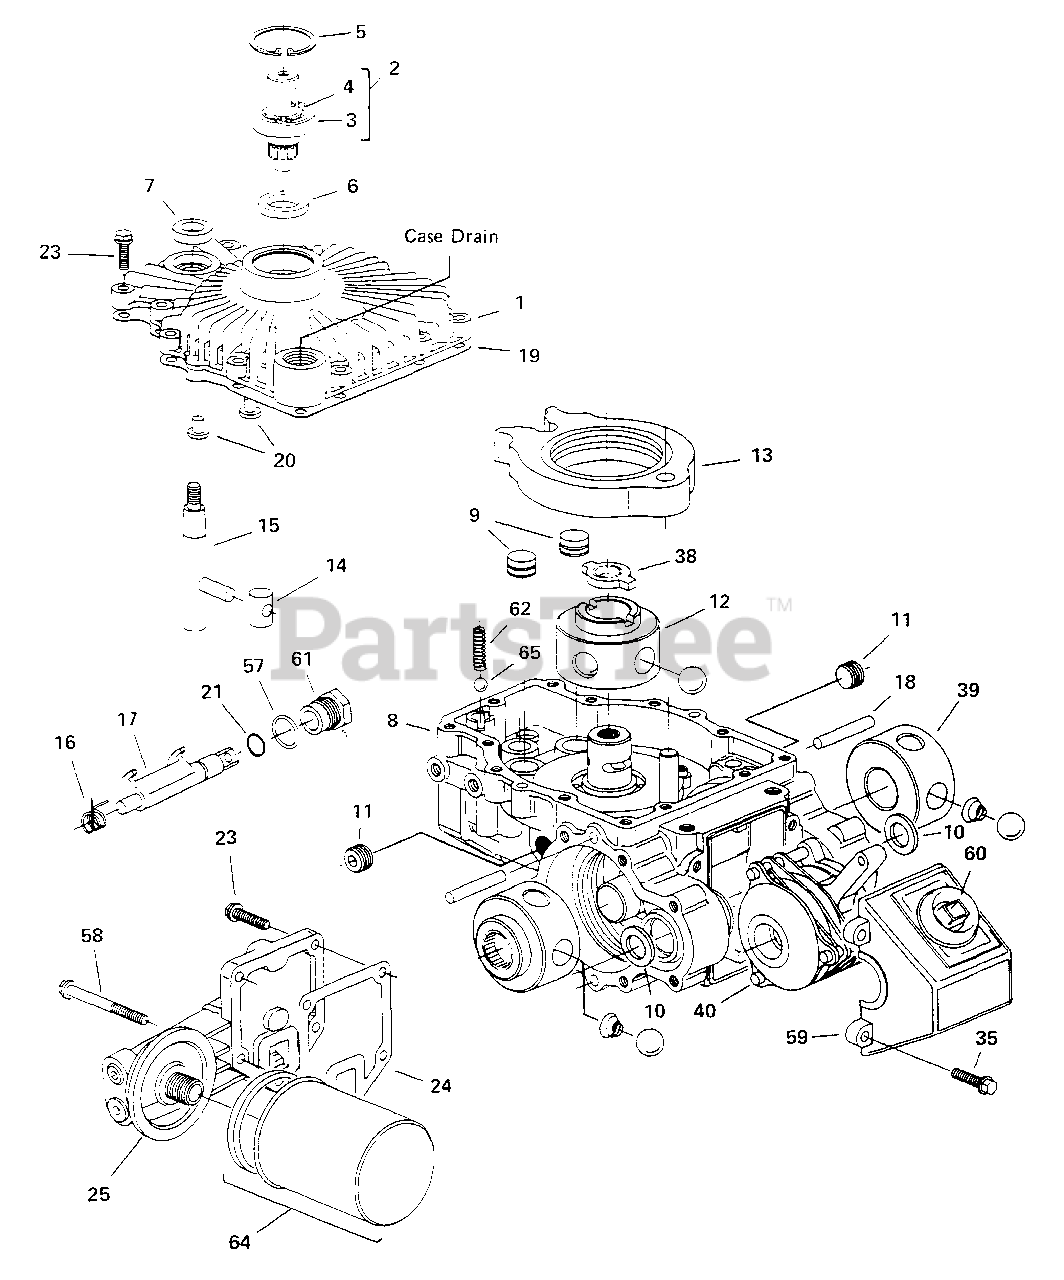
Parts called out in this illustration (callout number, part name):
1	COVER, Subassembly (S/A)
2	SHAFT, Input, S/A (Incl. 3 & 4)
3	BEARING
4	RING
5	RING, Retaining, Internal
8	HOUSING, S/A, Clockwise
9	PISTON, Quieting, S/A
10	SEAL, Lip, Radial
11	PLUG, Socket Pipe
12	PUMP, Rotor-Ball Pin, S/A
13	CAM RING, S/A
15	CONTROL SHAFT, S/A
16	SPRING, Dump Valve
19	GASKET, Cover
23	CAPSCREW, Hex, Flange, 1/4-20
24	GASKET, Filter Base
25	FILTER BASE, S/A
35	SCREW, 1/4-20 Self Tap
39	MOTOR ROTOR-BALL, A & B S/A, 15T
40	BRAKE, Parking, Assembly
57	O-RING, Fitting
58	SCREW, 1/4-20 Hex Flange
59	COVER, Parking Brake
62	SPRING, Relief Valve
64	FILTER, Oil (w/Seal), Special-10 Micron
65	BALL, Grade 200
65	GASKET OVERHALL KIT (Incl. Ref. Nos. 19, 22 & 24)
